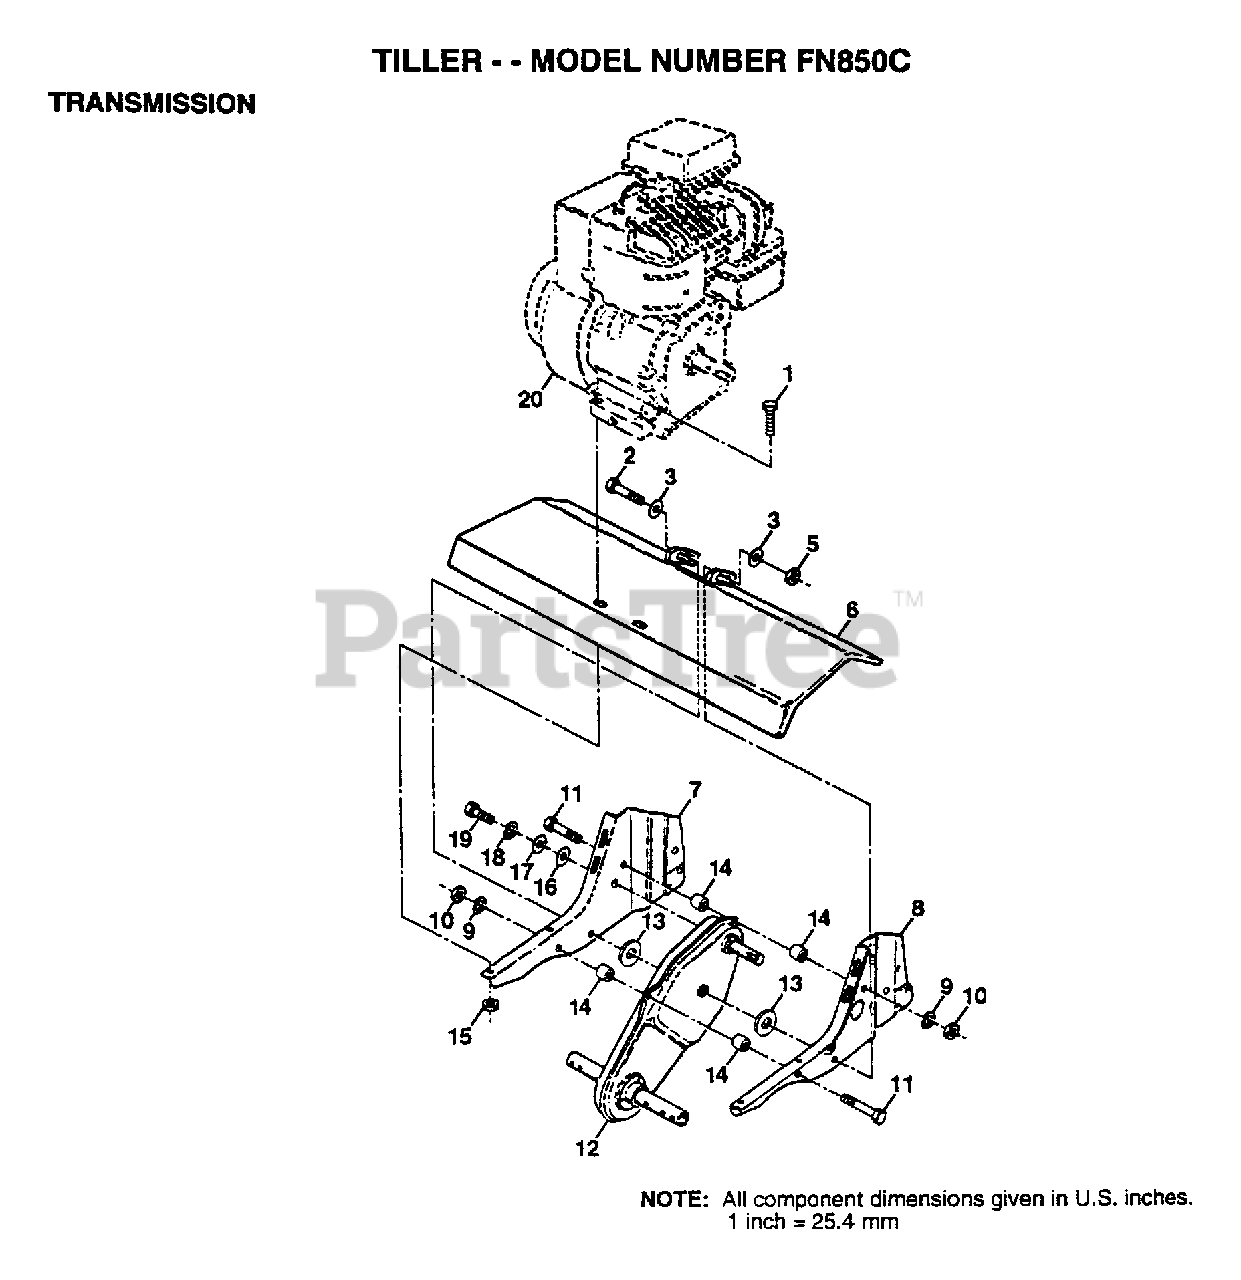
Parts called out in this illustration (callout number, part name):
1	BOLT.HEX.5/16-1.5
2	BOLT HEX 3/8-16
3	WASHER
5	NUT
6	"SHIELD, TINE"
9	LOCKWASHER
10	NUT.HEX.5/16-18
14	SPLIT SPACER RT
16	WASHER
17	WASHER
18	LOCKWASHER
19	BOLT
